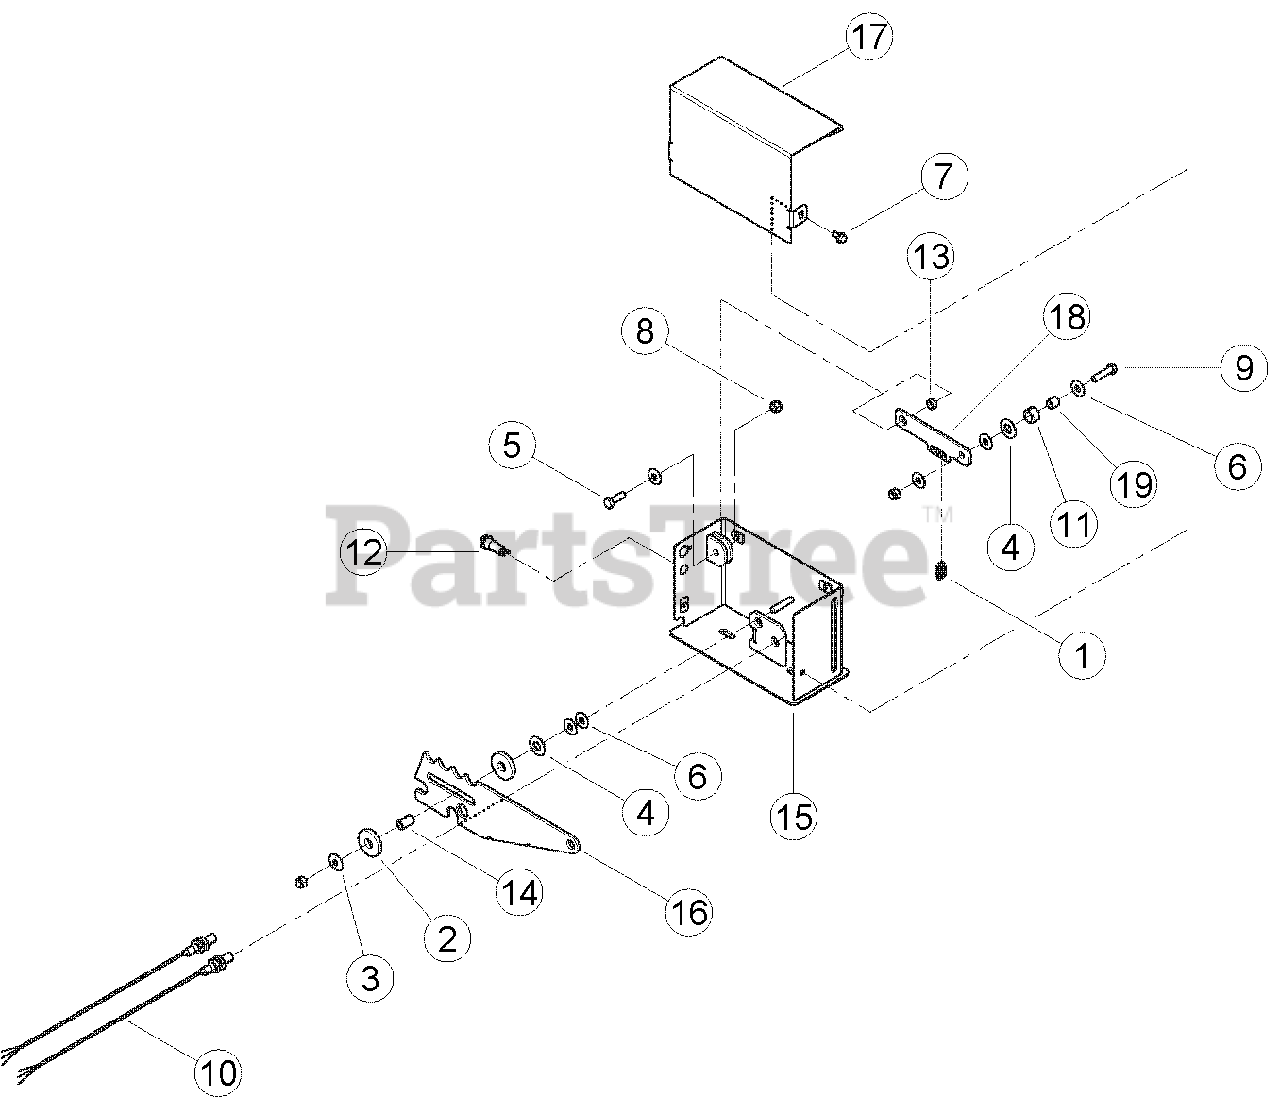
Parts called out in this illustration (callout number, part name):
1	SPRING, CONTROL BAR
2	WASHER, UHM SPACER .515 ID X 1.50 OD
3	WASHER, SPRING
4	WASHER, 1/2 SAE FLAT ZP
5	BOLT, 5/16 X 1 HHCS GR5 NC ZP
6	WASHER, 5/16 FLAT ZP
7	BOLT, 1/4 X 1/2 SERR FLANGE GR5 ZP
8	NUT, 5/16 NYLOCK
9	BOLT, 5/16 X 1-1/4 HHCS GR5 NC ZP
10	SENSOR, PROXIMITY (SERVICE REPLACEMENT PART)
11	ROLLER, NYLON .750 OD X .502 ID X .440
12	LED, TRI-COLOR 12V 3-TERMINAL BASE
13	SPACER, IDLER PIVOT
14	SPACER, .50 X .775
15	WELDMENT, SWITCH BOX
16	BAR, SWITCH CONTROL
17	COVER, CONTROL BOX
18	LINK, DETENT
19	SPACER, .50 OD X .35 ID X .47
